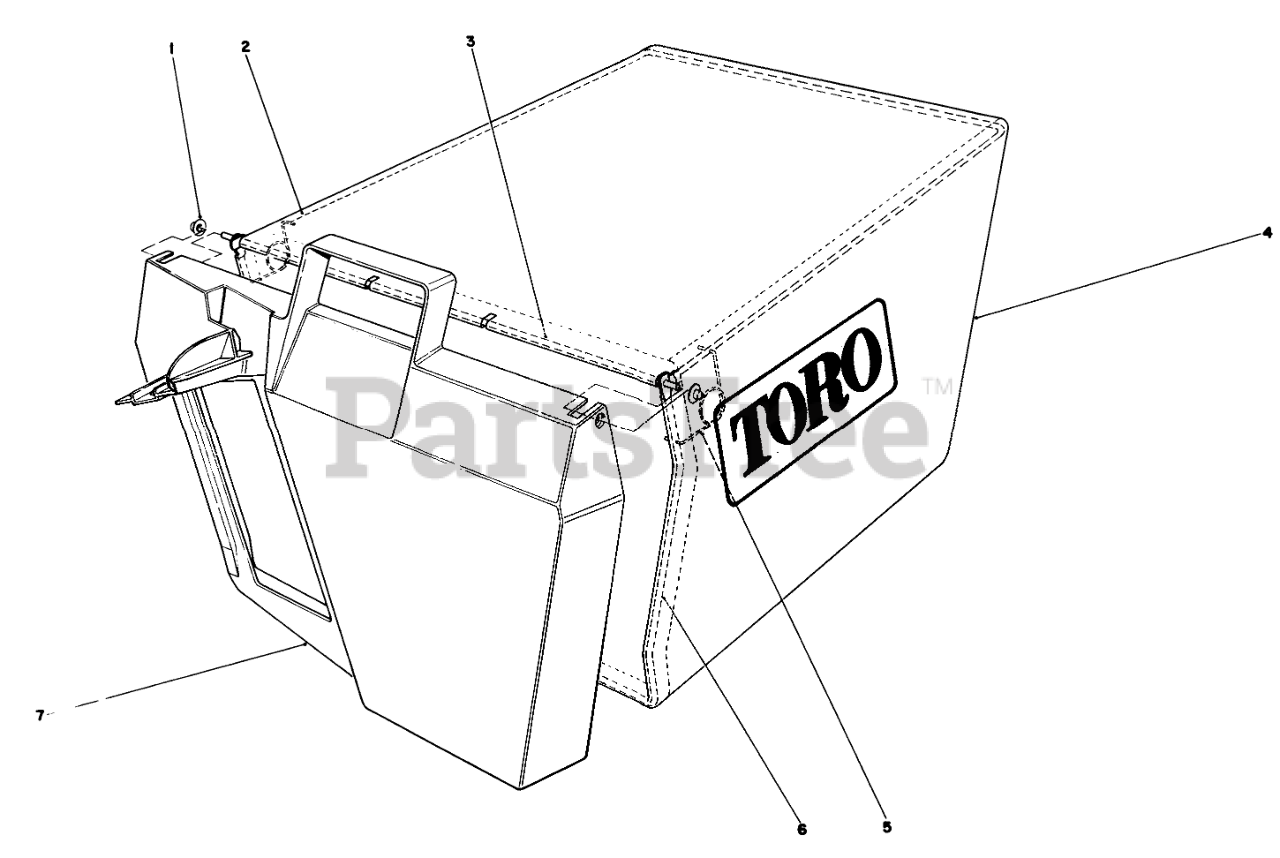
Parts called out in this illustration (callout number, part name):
1	NUT-PUSH
2	FRAME-BAG, UPPER
3	HINGE-DOOR, BAG
4	Bag
5	SPRING
6	BAG FRAME
7	Door Grass Bag
